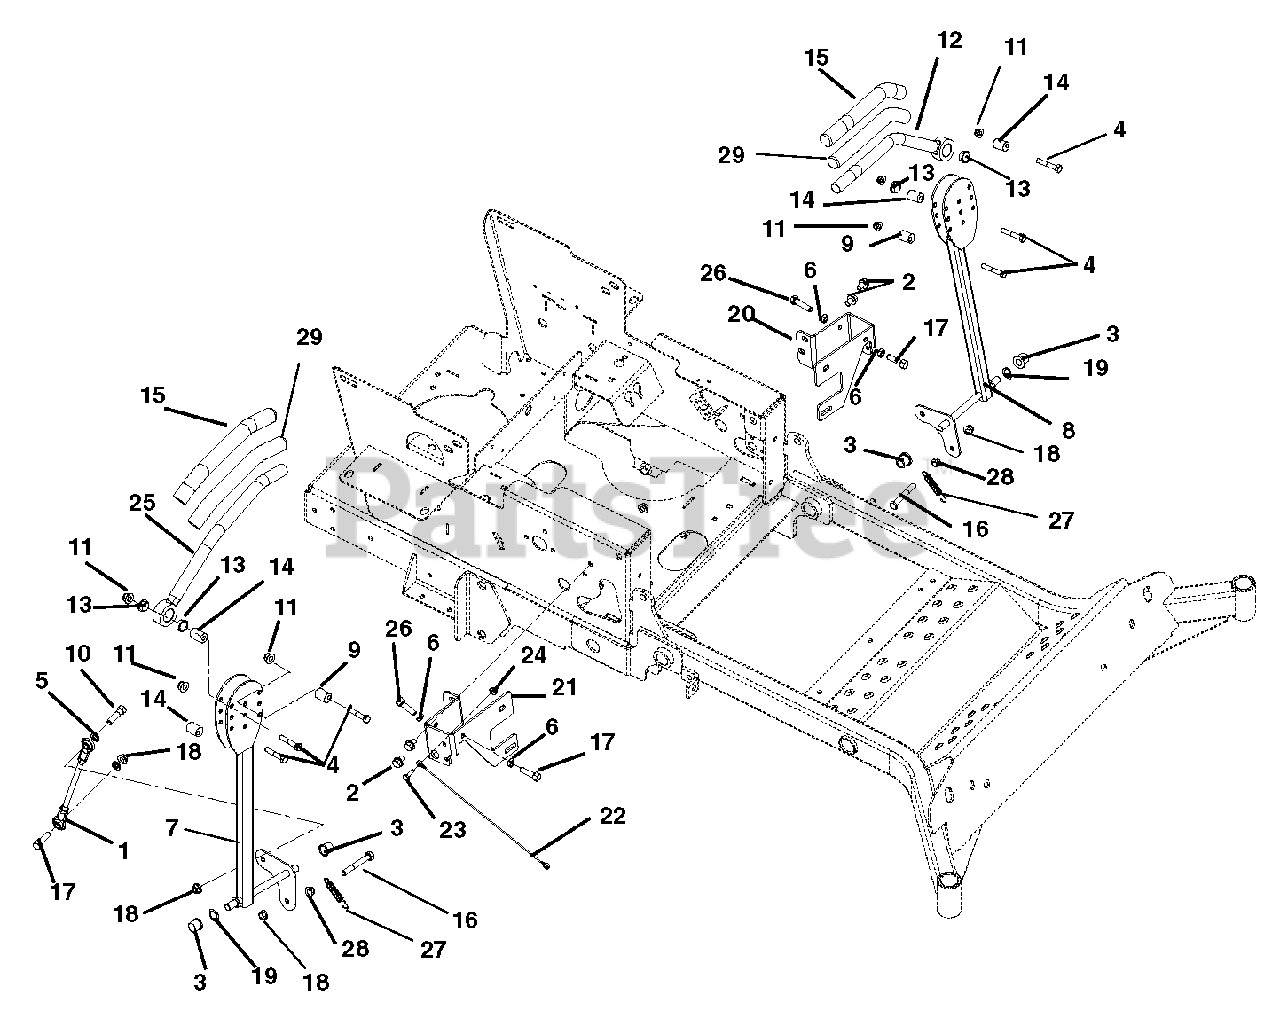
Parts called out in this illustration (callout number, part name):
1	Assembly, Steering Linkage
2	Screw, Tapping .38-16 x .50 Hex Washer Head
3	Bushing, Flange .515 x .750 x .745 x 1.00 Nylon
4	Bolt, Hex .31-18 x 1.75 Grade 5
5	Washer, Locking .38 x .094
6	Nut, Hex Jam .375-16
7	Weldment, RH Control Arm
8	Weldment, LH Control Arm
9	Eccentric
10	Bolt, Hex .38-16 x 1.50 Grade 5
11	Nut, Nyloc Flange .375-16
12	Handle Weldment Left-Hand
13	Bushing, Flange Nylon .762 x 1.48 x .44
15	Grip, Handlebar
16	Bolt, Hex .38-16 x 2.75 Grade 5
17	Bolt, Hex .38-16 x 1.25 Grade 5
18	Nut, Nyloc Flange 3/8-16
19	Wave Washer
20	Stop, Steering-Left Hand
21	Stop, Steering-Right Hand
22	Cable, 12.0 LANYARD, Nylon
23	Bolt-Hex .25-20 x .75 Grade 5
24	Nut, Nyloc Flange .25-20
25	Handle Weldment Right-Hand
26	Bolt, Hex .38-16 x .75 Grade 5
27	Spring, External,.061 x .50 x 3.0
28	Nut-Spin Lock-Flange .375-16
29	Tube, .88ID x 1.00OD x 10.75
